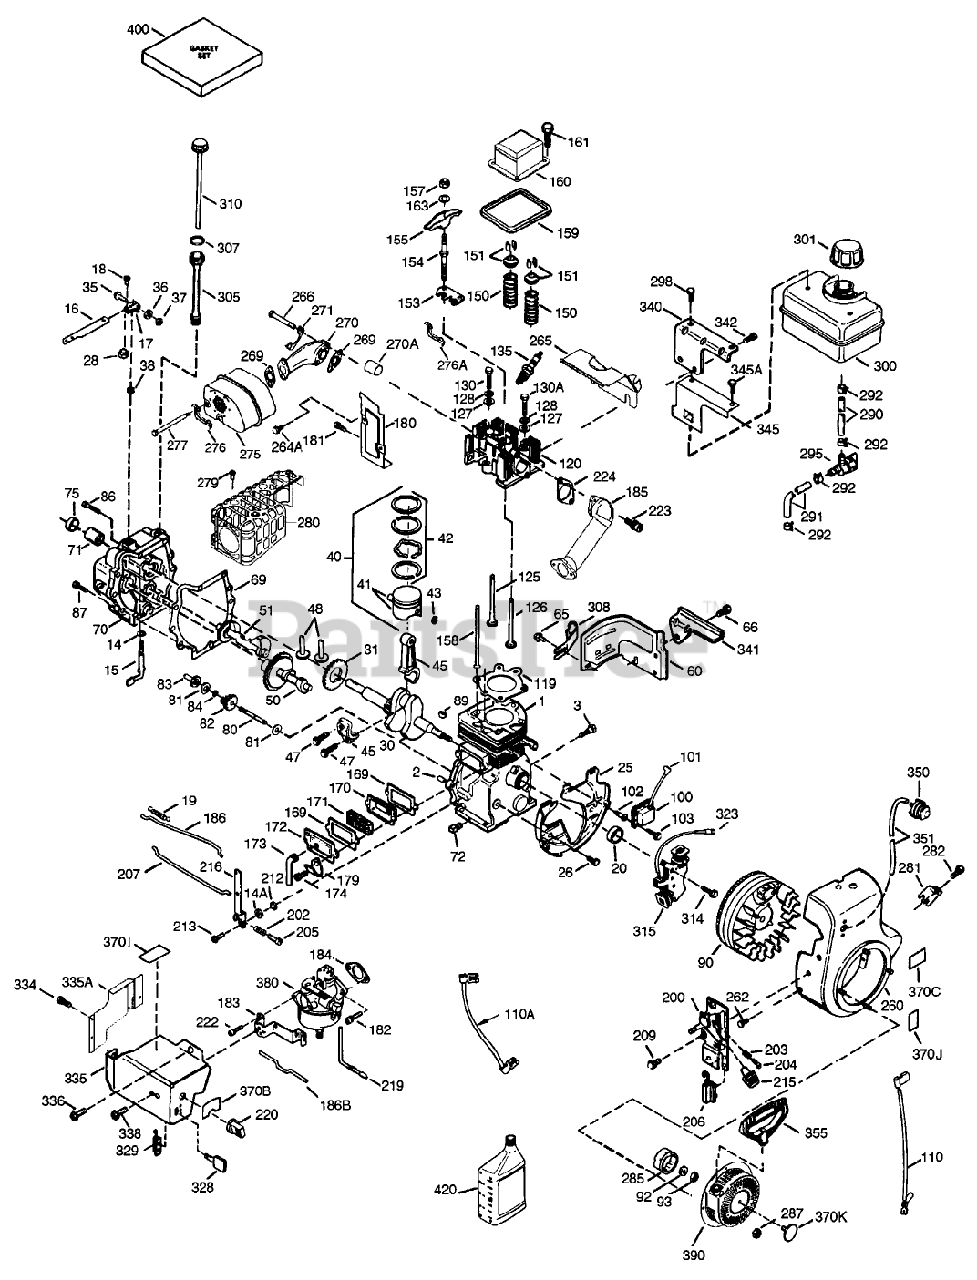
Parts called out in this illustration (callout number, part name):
1	Cylinder (Incl. 2, 20, 72 80)
2	Pin-Dowel
3	Screw (1/4-20x1/2)
14	Washer-Flat
14A	Washer
15	Governor Rod (Incl. Ref.#14 38)
16	Governor Lever
17	Clamp-Lever, Governor
18	Screw (T-15, 8-32x7/16)
19	Throttle Spring
20	Seal-Oil
25	Baffle-Housing, Blower
26	Screw (1/4-20x19/32)
28	Nut-Lock
30	Crankshaft
31	Counterbalance Gear
35	Screw
36	Washer-Lock
37	Nut-Lock
38	Ring-Retaining
40	Piston Pin and Ring ASM (STD)
40	Piston Pin and Ring ASM (.010)
40	Piston-Pin Ring Set (.020" OS)
41	Piston Pin Ass-y(Std.)(Incl. 43)
41	Piston Pin Ass-y (.010" OS)(Incl. 43)
41	Piston Pin Ass-y.(.020" OS)(Incl. 43)
42	Ring Set (STD)
42	Ring Set (.010)
42	Ring Set (.020)
43	Retaining Ring-Piston Pin
45	Connecting Rod ASM (Incl. Ref. #47)
47	Bolt-Rod, Connecting
48	Lifter-Valve
50	Camshaft
51	Counterbalance Weight
60	Extension-Housing, Blower
65	Screw (10-24 x 9/16)
66	Screw (1/4-20x19/32)
69	55072/75/86/89 TWO
70	Cylinder Cover (Incl. Ref. #14, 15, 38, 71, 75)
71	2025A77 WIZARD ROTA
72	Plug-Drain, Oil (SQH 1/4-18)
75	Seal-Oil
80	Governor Shaft
81	Washer
82	Gear-Asm Governor
83	Governor Spool
84	Ring-Retaining
86	Screw (1/4-20x1-3/16)
87	Screw (1/4-20x1-11/16)
89	Key-Flywheel
90	Flywheel ASM
92	Washer-Belleville
93	Nut-Flywheel
100	Solid State ASM
101	Cover-Spark Plug
102	Stud-Mounting, Solid State
103	Screw (T-15, 10-24 x 15/16)
110	Wire-Ground
110A	Wire-Ground (Green, 5.5)
119	Cylinder Head Gasket
120	Cylinder Head
125	Valve-Exhaust (STD)
125	Valve-Exhaust (1/32)
126	Valve-Intake (STD)
126	Intake Valve (1/32)
127	Washer-Flat
128	Washer-Belleville
130	Screw (5/16-18 X 2-1/2)
130A	Screw (T-30, 1/4-20x15/32)
135	Spark Plug-Resistor (R N 4C)
150	Spring-Valve
151	Keeper-Spring, Valve
153	Guide-Rod, Push
154	Stud-Arm, Rocker
155	Arm-Rocker
157	Nut-Jam
158	Rod-Push
159	Gasket-Cover, Rocker Arm
160	Cover-Arm, Rocker
161	Screw
163	Washer
169	Gasket-Cover, Valve
170	Body-Breather
171	Element-Breather
172	Cover-Valve
173	Tube-Breather
174	Screw
179	Retainer Clip
180	Extension-Housing, Blower
181	Screw (10-24 x 9/16)
182	Screw (T-30, 1/4-20 X 27-32)
183	Bracket-Choke
184	Gasket-Carburetor To Intake Pipe
185	Pipe-Intake
186	Governor Link
186B	Spring-Choke
200	Bracket-Control (Incl. Ref. #203, 204 and 206)
202	Compression Spring
203	Spring-Compression
204	Screw (T-10, 5-40x7/16)
205	Screw
206	Terminal
207	Choke Link
209	Screw (10-32 x 1/2)
212	Bushing
213	Screw
215	Knob-Control
216	Lever-Adjusting
219	Rod-Choke
220	Knob-Control
222	Screw (10-32 x 1/2)
223	Screw (T-30, 5/16-18 X 7/8)
224	Gasket-Pipe
260	Blower Housing
262	Screw
264A	Screw (1/4-20 X 5/8)
265	Cover-Head, Cylinder
266	Screw (5/16-18 X 1-9/32)
269	Gasket-Manifold, Exhaust
270	55107 SNWTHWR ATTCH
270A	Liner-Port, Exhaust
271	Plate-Locking
275	Muffler
276	Plate-Locking
276A	62513 SNWTHWR W/284
277	Screw (5/16-18 X 4-1/2)
279	Screw
280	Cylinder (Incl. 2, 20 150)
281	Screw
282	Screw (8-32 x 3/8)
285	Cup-Starter
287	Nut and Lock Washer (1/4-28)
290	Line-Fuel (8.62)
291	Line-Fuel
292	Clamp-Line, Fuel
295	Valve-Shut Off, Fuel
298	Screw (1/4-15x7/8)
300	Fuel Tank (Incl. 292 301)
301	Cap-Fuel
305	Tube-Fill, Oil
307	O-Ring
308	Clip-Tube, Fill
310	Dipstick
314	Screw (1/4-20 x 3/4)
315	Alternator Coil (18 watt)(Incl. 323)
323	Terminal
328	Key-Ignition
329	Terminal
334	Screw (8-32 X 5/16)
335	Carburetor Cover
335A	Cover-Carburetor
336	Screw (10-32x1/2)
338	Screw (10-32 x 1/2)
340	55073/76/87/90 SNWT
341	Bracket-Fuel Tank
342	Screw (5/16-18 X 7/8)
345	Baffle-Heat
345A	Screw (5/16-18 X 1-9/32)
350	Primer ASM
351	Line-Primer
355	Handle-Starter, Mitten Grip
370B	Control Decal
370C	Decal-Primer, International Symbol
370I	Decal-Warning (Bilingual)
370J	Throttle Decal
370K	Decal-Tecumseh Logo for Top of Recoil Starter
380	Carburetor (Incl. Ref.# 184)
390	Starter-Rewind
400	Gasket Set
420	Oil-Engine (SAE 5W30)
